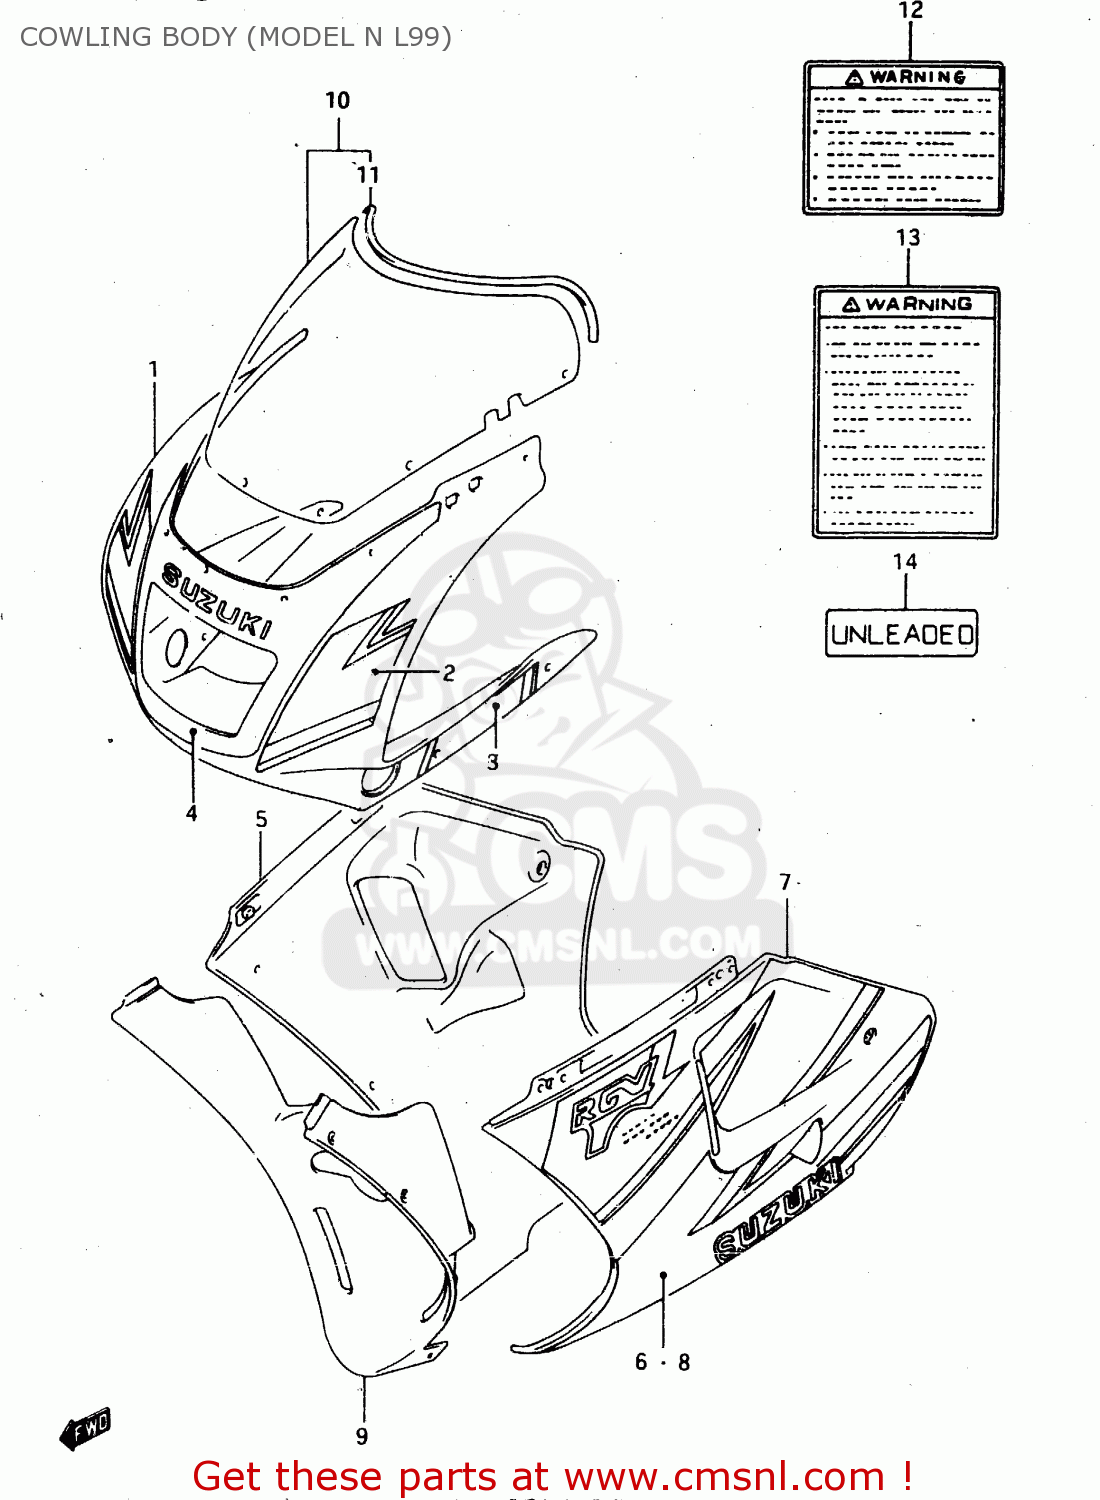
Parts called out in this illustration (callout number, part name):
1	COWLING ASSY, BODY (WHITE)
2	TAPE SET, FRONT
3	TAPE,COWL UPP.
4	TAPE, ZECKEN
5	COWLING ASSY, UNDER RH (WHITE)
6	TAPE SET, UNDER RH
7	COWLING,UND.L
8	TAPE SET, UNDER LH
9	COWLING, UNDER CENTER (WHITE)
10	SCREEN SET,WIND
11	MOLDING WINDSCREEN
12	LABEL
13	LABEL (WARNING SCREEN)
14	LABEL,CAUTION
